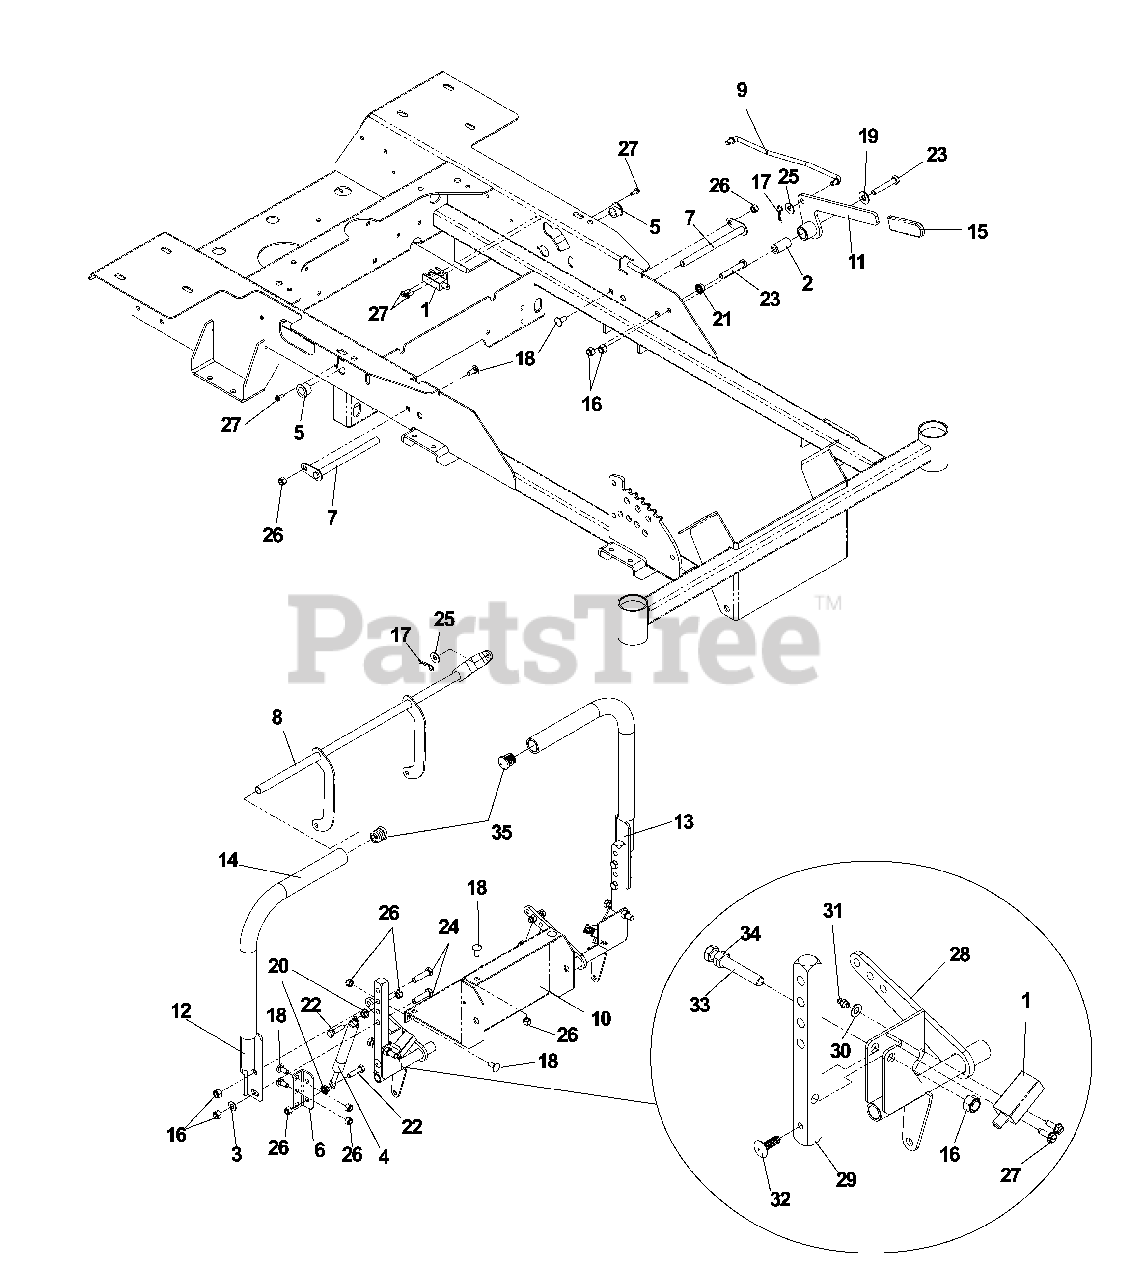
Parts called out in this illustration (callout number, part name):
1	SWITCH, INTERLOCK
2	BUSHING, SLEEVE
3	WASHER, 3/8 DISC SPRING SPEC
4	DAMPENER
5	PLASTIC BUSHING
6	DAMPENER BRACKET
7	PIVOT SHAFT
8	BRAKE SHAFT
9	BRAKE LINKAGE
10	BATTERY TRAY
11	BRAKE LEVER WELDMENT
12	LEVER, DRIVE, RT
13	LEVER, DRIVE, LT
16	NUT 3/8-16 NYLOC
17	HAIRPIN #2
18	BOLT 5/16C X 3/4" CARRIAGE
19	WASHER 3/8 FLAT
20	NUT 5/16C WHIZ
21	NUT 3/8C WHIZ
22	HCS 5/16C X 1 1/4
23	HCS 3/8C X 2 1/4
24	HCS 3/8C X 1 1/2
25	WASHER 5/16 FLAT
26	NUT 5/16 NYLOC
27	SCREW #10 X 1/2 SELF TAPPING
28	CONTROL WELDMENT, RIGHT
29	CONTROL ARM
31	ZERK
32	RIVET, NYLON PUSH-IN
33	HCS 3/8-16 X 2-1/2 TPBLT
34	NUT 3/8C CENTERBLOCK
35	END PLUG 15/16` (BLACK)
